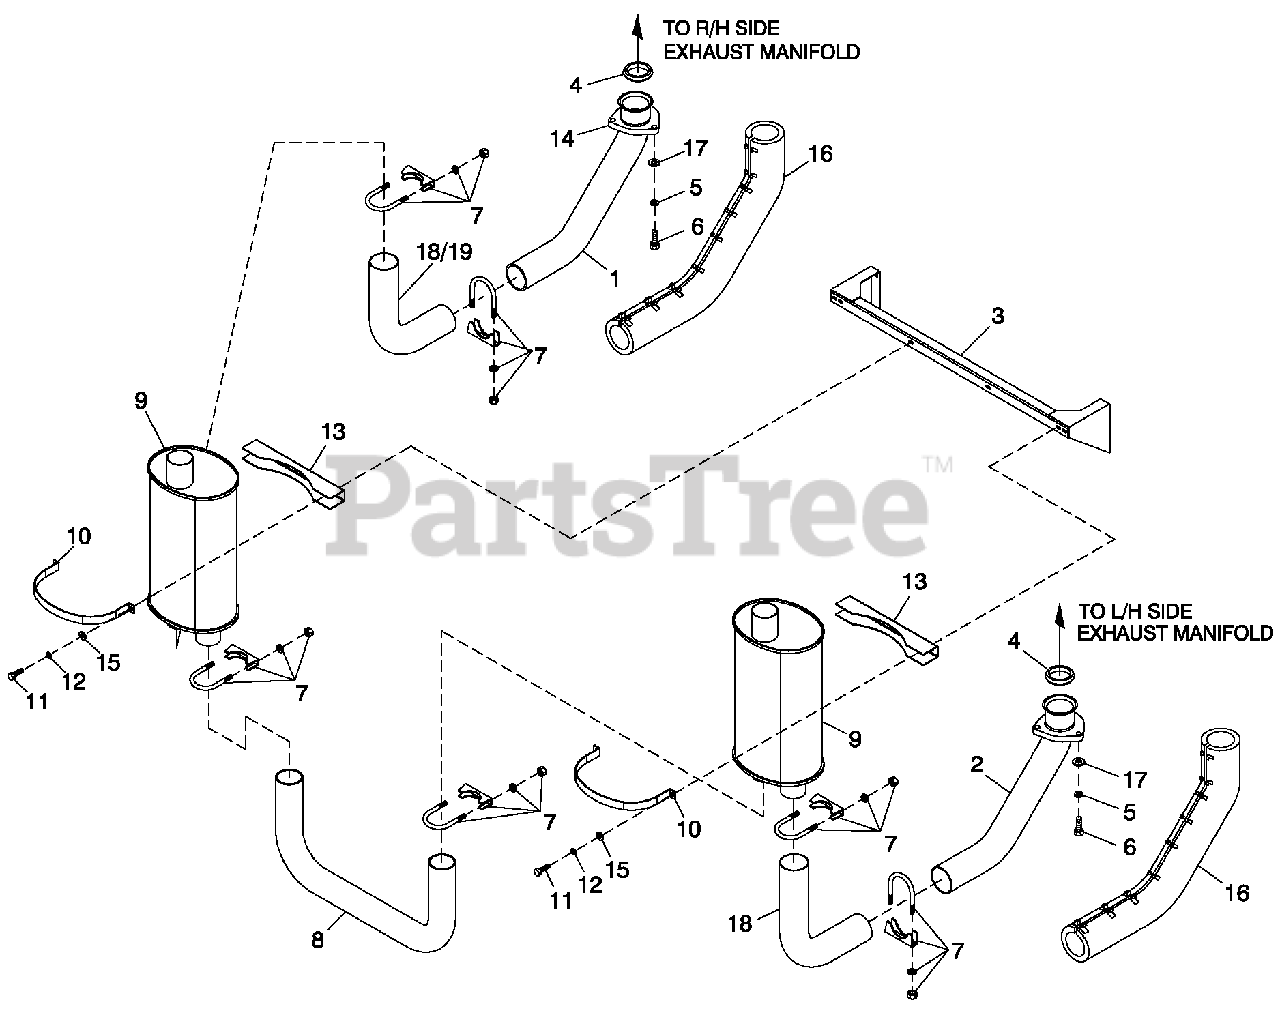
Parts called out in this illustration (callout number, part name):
1	PIPE EXH MANIFOLD 6.8L C3 RH (6.8L 70KW)
2	PIPE EXH MANIFOLD 6.8L C3 LH (6.8L 70KW)
3	BRKT MUFFLER
4	RING GASKET, 2.5DIA
5	WASHER LOCK M10 SS
6	SCREW HHC M10-1.5 X 50 SS FTH
7	BOLT U 3/8-16 X 2.62
8	PIPE EXHAUST CROSSOVER
9	MFLR 7" X 9" X 25" (2) 2.5" IN/2.5" OUT
10	MUFFLER STRAP
11	SCREW HHC M6-1.0 X 16 G8.8
12	WASHER LOCK M6-1/4
13	MUFFLER BRACKET STIFFENER
14	FLANGE EXHAUST
15	WASHER FLAT 1/4-M6 ZINC
16	EXHAUST BLANKET 800MM LG (6.8L 70KW)
17	WASHER FLAT 3/8 SS
18	PIPE LH MUFFLER SIDE
19	PIPE RH MUFFLER SIDE
